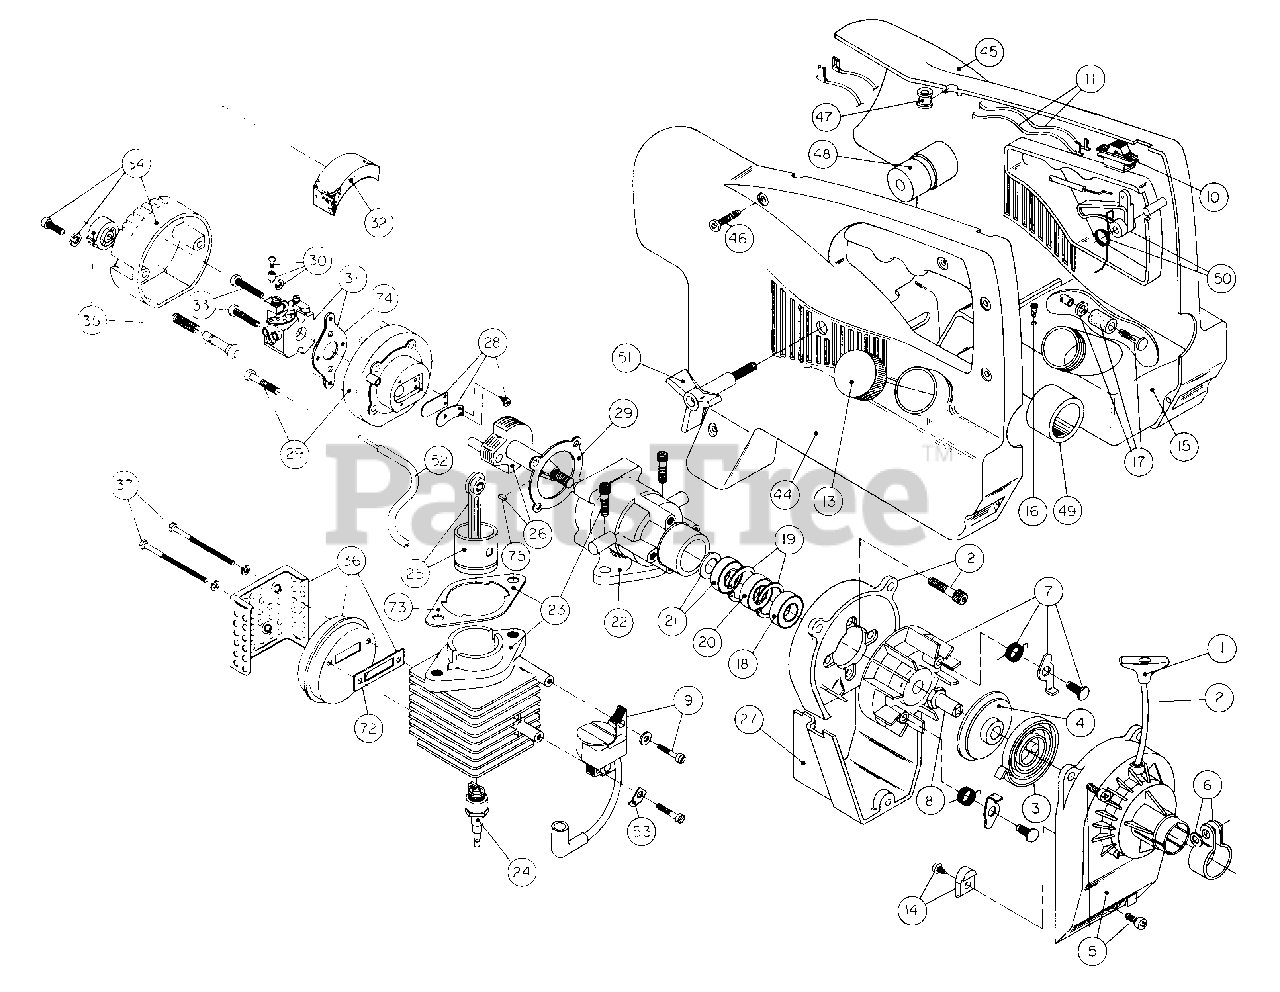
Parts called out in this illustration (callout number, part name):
1	Pull handle
2	Rope
3	Recoil spring
4	Recoil pulley assembly
5	Starter housing assembly
6	Upper clamp assembly
7	Flywheel assembly
8	Square drive nut
9	Module assembly
10	Switch assembly
11	Wire leads assembly
12	Shroud assembly
13	Fuel cap assembly
14	Pulley retainer assembly
15	Fuel tank
16	Fuel tank vent
17	Fuel line assembly
18	Outer bearing
19	Snap ring assembly
21	Inner bearing assembly
22	Crankcase
23	Cylinder assembly
24	Spark plug
25	Piston & rod assembly
26	Power shaft assembly
27	Shroud extension
28	Reed assembly
29	Carburetor mount assembly
30	Throttle adjustment assembly
31	Carburetor assembly (Walbro)
32	Air cleaner filter
33	Carburetor mounting screw assembly
34	Air cleaner cover assembly
35	Choke knob assembly
36	Muffler assembly
37	Muffler mounting bolt assembly
44	Right side cowl
45	Left side cowl
46	Cowl screw assembly
47	Rope guide
48	Engine mount assembly
49	Grommet tube
50	Throttle trigger assembly
51	Head adjustment knob
52	Throttle wire assembly
53	Ground tab
72	Exhaust gasket (10 pack)
73	Cylinder gasket (10 pack)
74	Carburetor gasket (10 pack)
75	Flywheel key (10 pack)
